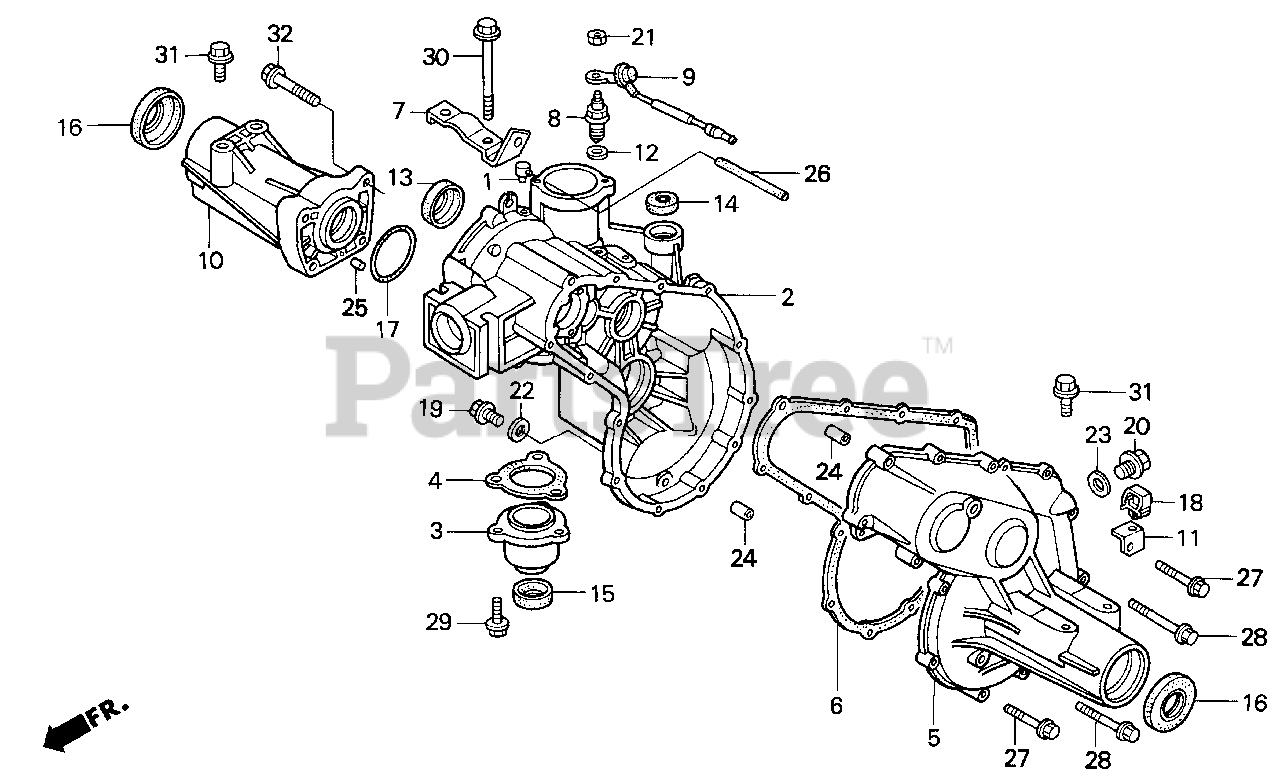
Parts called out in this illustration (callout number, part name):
1	JOINT, BREATHER
2	CASE, R. TRANSMISSION
3	HOLDER, INPUT SHAFT
4	GASKET, INPUT SHAFT HOLDER
5	CASE, L. TRANSMISSION
6	GASKET, TRANSMISSION CASE
7	PLATE, TRANSMISSION
8	SWITCH, NEUTRAL
9	WIRE, NEUTRAL SWITCH
10	HOUSING, RR. AXLE
11	BRACKET, SUB-HARNESS
12	WASHER, NEUTRAL SWITCH
13	OIL SEAL (22X32X7)
14	OIL SEAL (14X24X6) (ARAI)
15	OIL SEAL (20X38X10)
16	OIL SEAL (25X52X7)
17	O-RING (40.9X2.1) (NOK)
18	CLIP, HARNESS (7MM)
19	BOLT, DRAIN PLUG (12MM)
20	BOLT, DRAIN PLUG (20MM)
21	NUT, HEX. (4MM)
22	WASHER, DRAIN PLUG (12MM)
23	WASHER, DRAIN PLUG (20MM)
24	PIN A, DOWEL (8X14)
25	PIN, DOWEL (6X10)
26	BULK HOSE, VACUUM (5X3000) (5X260)
27	BOLT, FLANGE (6X35)
28	BOLT, FLANGE (6X45)
29	BOLT, FLANGE (8X28)
30	BOLT, FLANGE (8X85)
31	BOLT, FLANGE (10X25)
32	BOLT, FLANGE (10X40)
